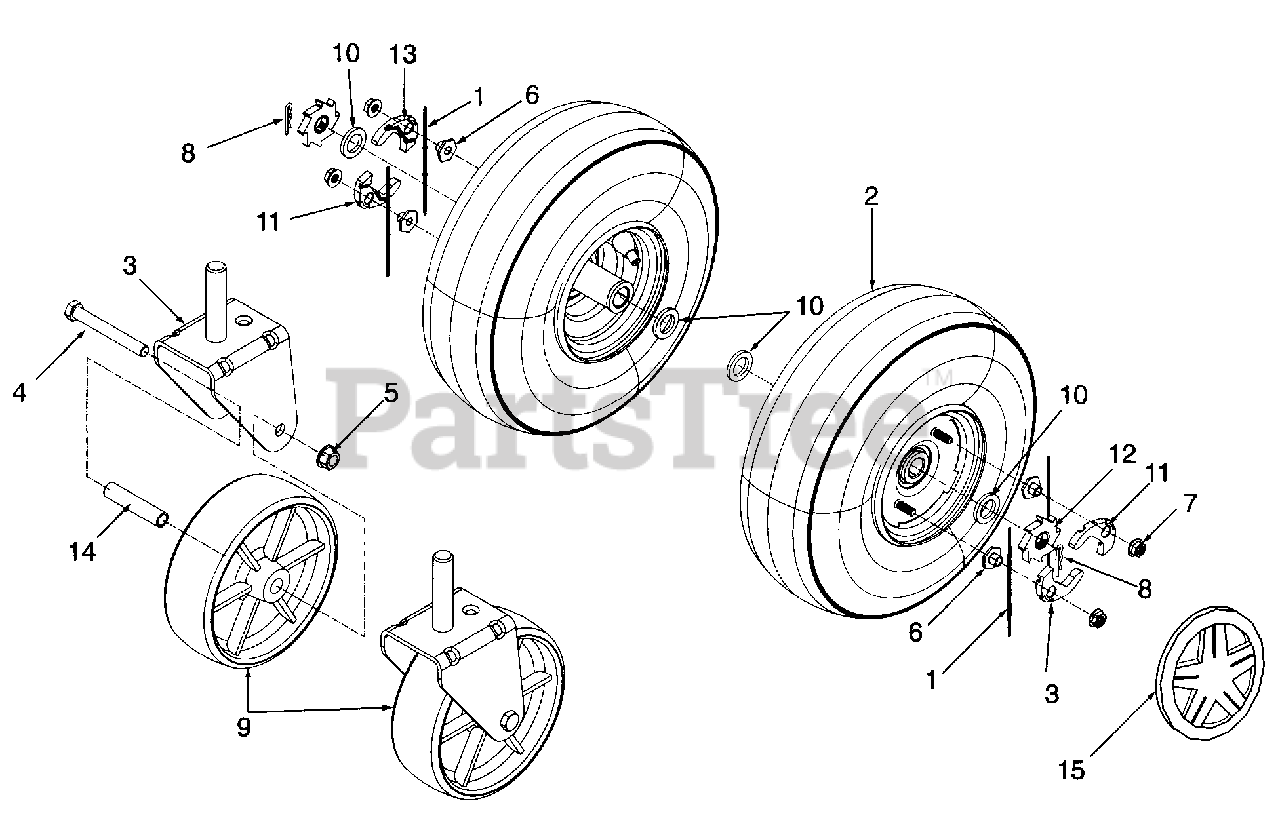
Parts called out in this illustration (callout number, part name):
1	Spring, Plastic Ratchet
4	Screw, Hex Cap, 3/8-16 x 3.0
5	Nut, Hex Flange Lock, 3/8-16
6	Nut, Special Hex 1/4-20
7	Nut, Hex Flange Lock, 1/4-20
8	Pin, Internal Cotter
9	Wheel, 6.00 x 2.00
10	Washer, Flat, .64 x 1.12 x .12
11	Pawl, LH .345 ID
12	Ratchet, Wheel, .5 Serr ID x 1.62
13	Pawl, RH .345 ID
14	Spacer, .384 ID x .5 OD x 2.3 Lg
15	Hubcap, 4.0 Beige
